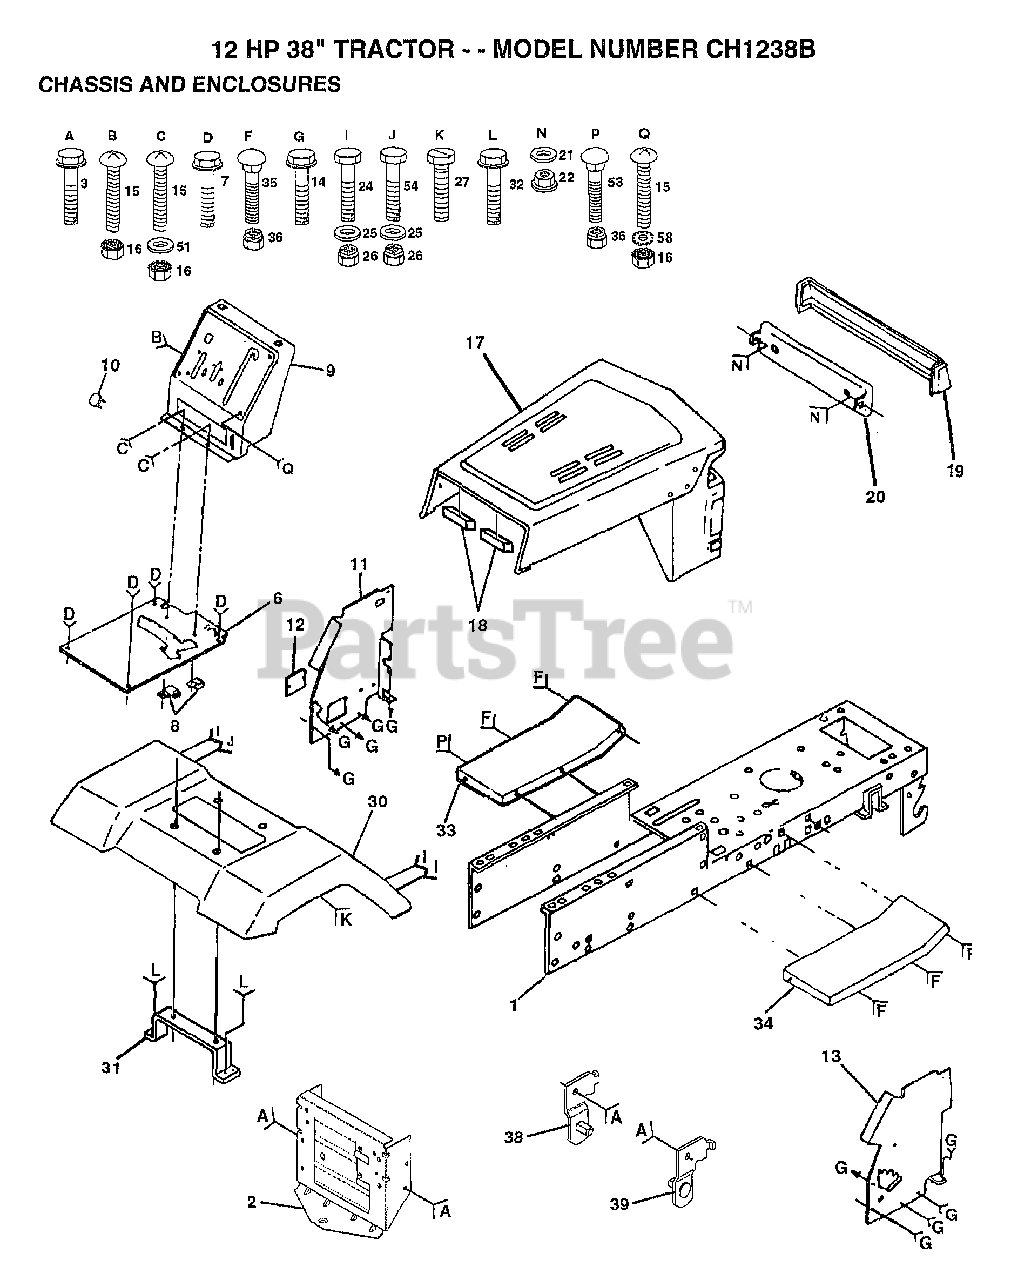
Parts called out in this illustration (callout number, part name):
3	SCREW
7	SCREW
8	CLIP T
9	DASH SILKSCRN 1
10	PLUG BUTTON T
11	PANEL DASH LH
12	COVER ACCESS
14	SCREW LT
15	SCREW
17	HOOD/GRILL ASM
21	WASHER PM
22	PAL NUT LT
25	WASHER
27	SCREW LT
30	FENDER
31	BRKT FENDER
32	SCREW
33	FOOTREST LH
34	FOOTREST RH
35	BOLT
38	BRACKET ASM LH
39	BRACKET ASM RH
51	WASHER
58	LOCKWASHER
